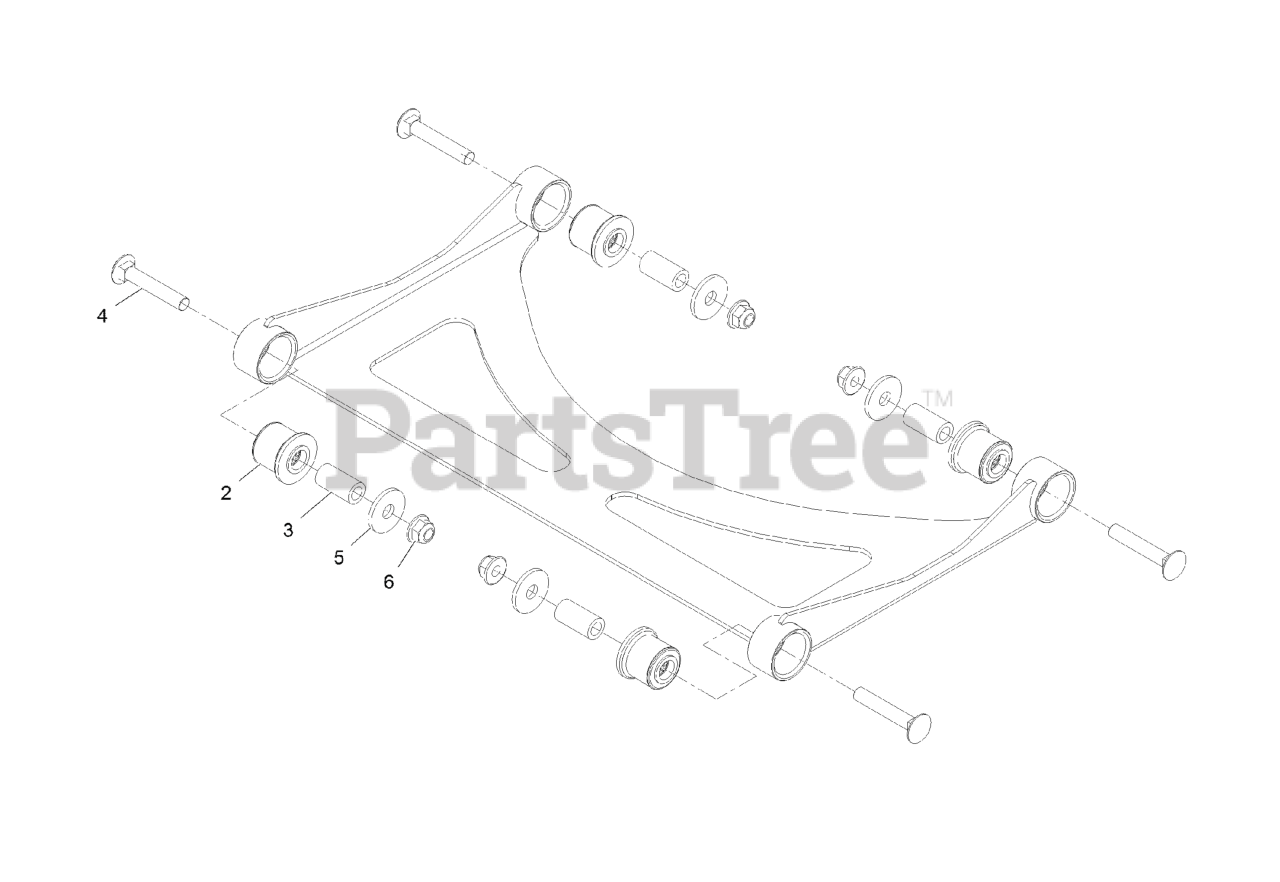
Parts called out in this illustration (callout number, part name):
2	BUSHING-RUBBER, SUSPENSION
4	Bolt-Carriage 3/8-16 X 2 1/4
5	WASHER
6	NUT-HF, NI
